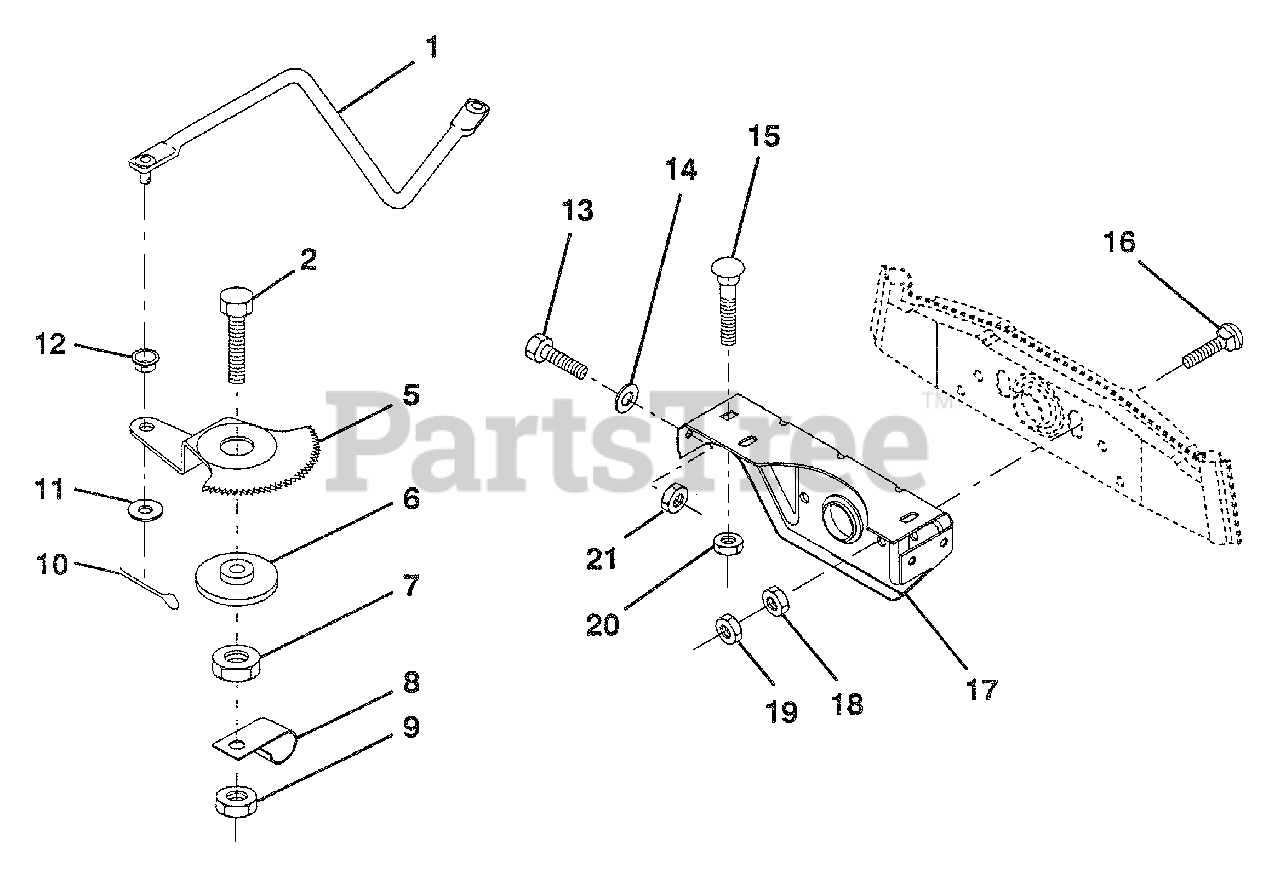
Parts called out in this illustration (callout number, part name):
1	Link, Drag
2	Bolt, Fin Hex 1/2-13 x 1-3/4
5	Gear, Sector
7	Nut, Heavy Hex Top Lock 1/2-13 UNC
8	Clip, Insulated
9	Nut, Crownlock 3/8-16
10	Pin, Cotter 1/8 x 3/4
11	Washer, 13/32 x 13/16 x 16 Ga.
13	Bolt, Hex Hd. 5/16-18 UNC x 1
14	Washer 11/32 x 7/8 x 16 Ga.
15	Bolt, Carriage 3/8-16 UNC x 3/4
16	Bolt, Carriage
17	Support, Front Axle
18	Nut, Fin Hex 3/8-16 UNC
19	Nut, Centerlock 3/8-16 UNC
20	Nut, Crownlock 3/8-16 UNC
21	Nut, Crownlock 5/16-18
